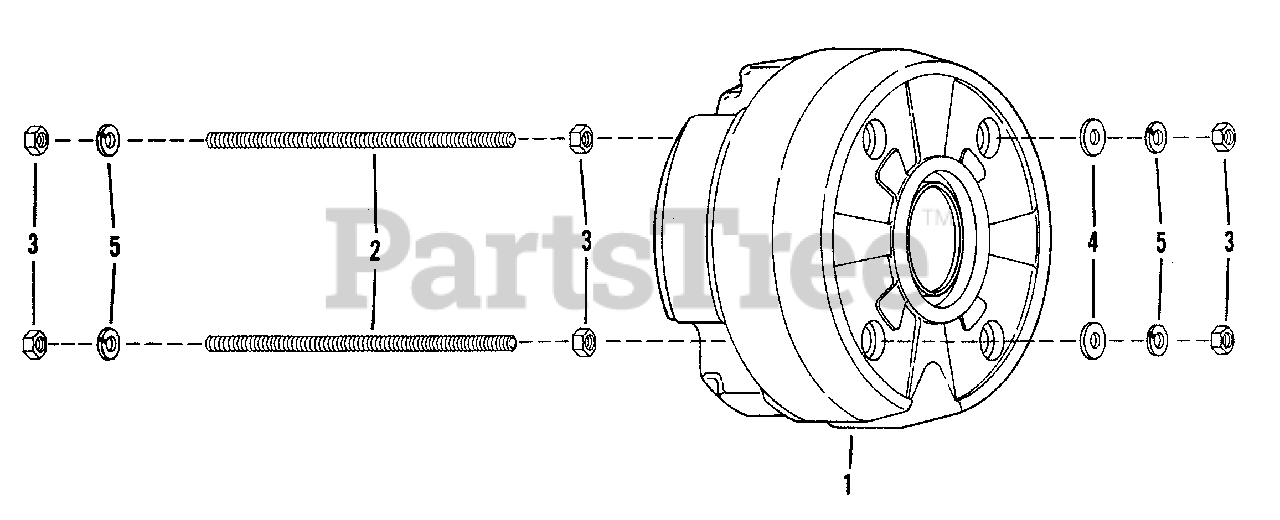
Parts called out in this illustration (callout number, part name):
1	Weight, Wheel
2	ROD, 1/2-13x9-1/2" Threaded
3	NUT, 1/2-13 Hex
4	WASHER, 1/2 Flat
5	WASHER, 1/2 Split Lock
